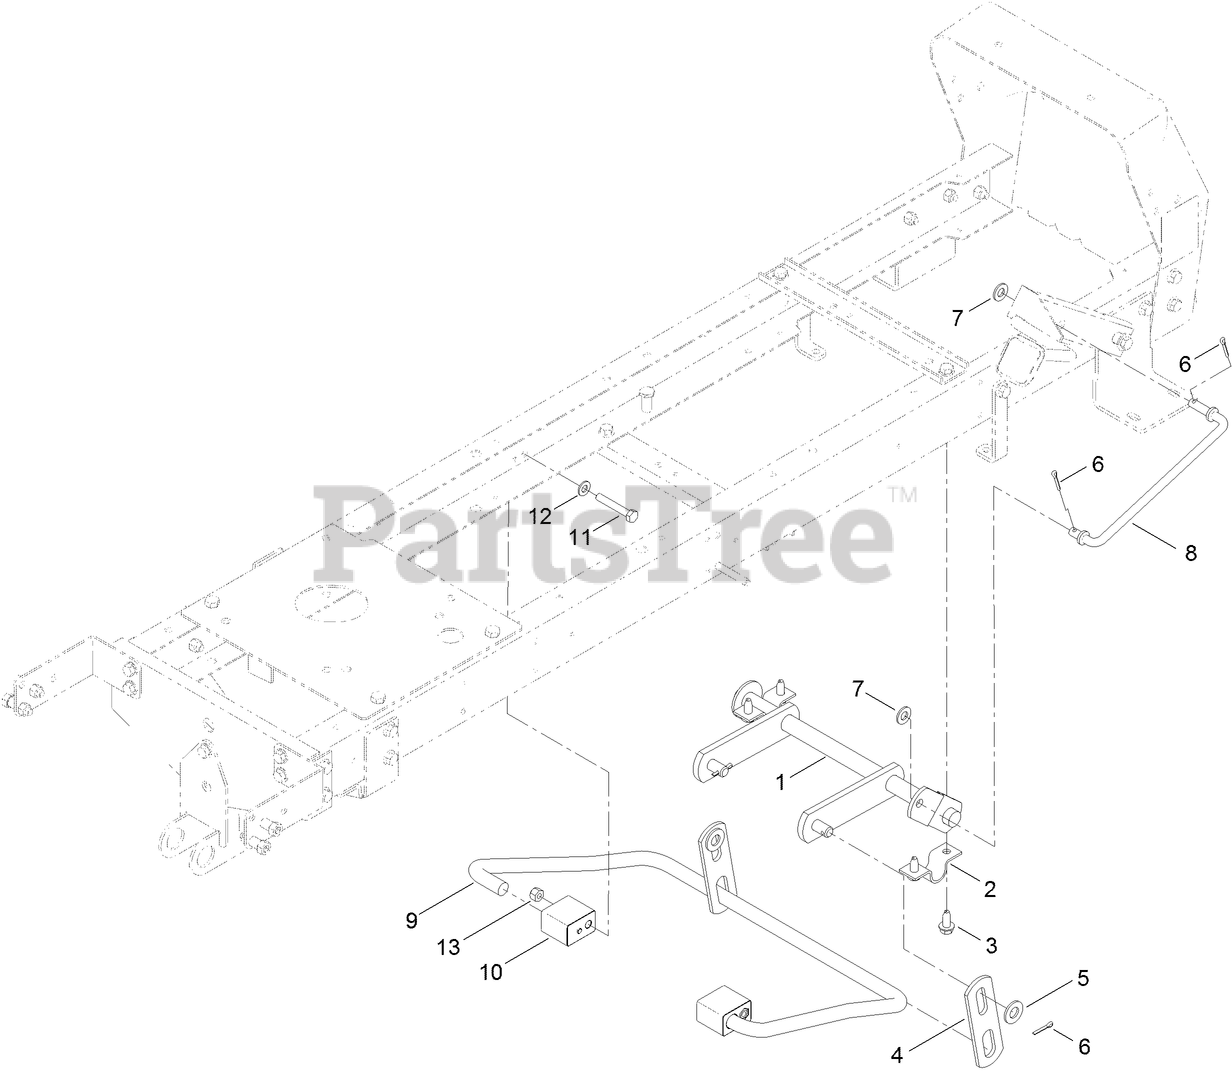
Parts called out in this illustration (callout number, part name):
1	ARM-LIFT
2	CLAMP-PIVOT, HOC
3	SCREW-HWH
4	LINK-LIFT
5	WASHER-FLAT
6	PIN-COTTER
7	WASHER-FLAT
8	LINK-ARM, LIFT
9	ARM-LIFT, REAR
10	BLOCK-PIVOT
11	SCREW-HH
12	WASHER-PLAIN
13	NUT-LOCK, NI
